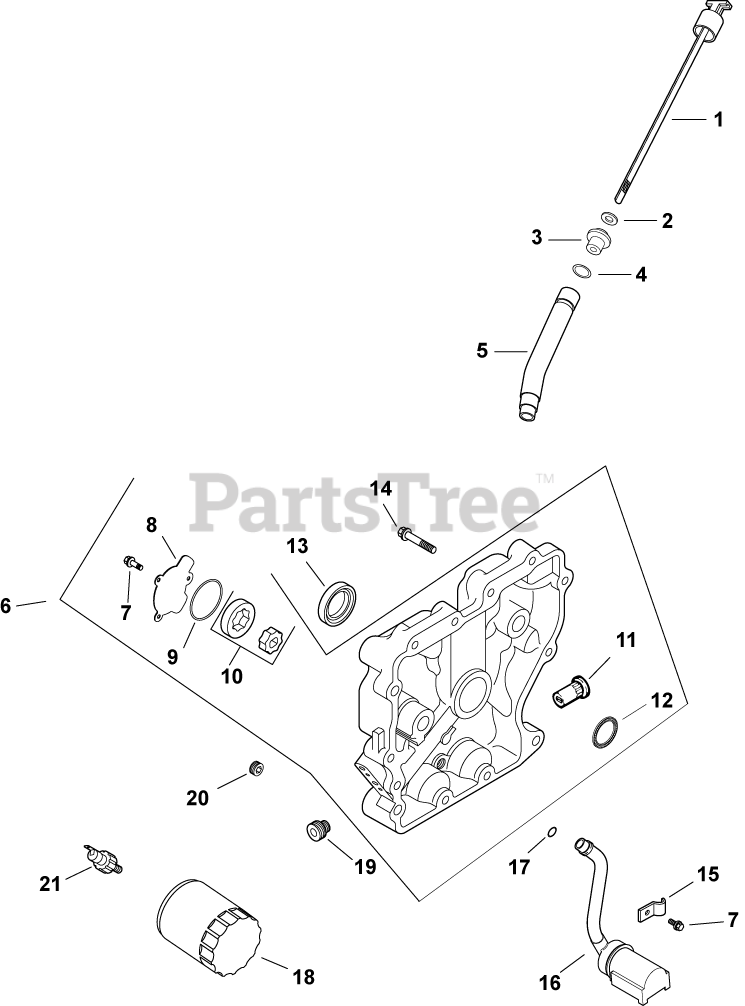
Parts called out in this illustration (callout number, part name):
3	SEAL USE 25 032 13-S
5	TUBE, OIL FILL
6	PLATE, CLOSURE & BEARING
7	SCREW,FLG THD FRM M5X0.8X16-(#25086398S)
8	COVER, OIL PUMP
9	O-RING (1.78" DIA)
10	PUMP ASSEMBLY, OIL
11	VALVE, OIL PRESSURE RELIEF
12	BEARING, CRANKSHAFT
13	SEAL, OIL
14	SCREW, FLG M8X1.25X45
16	KIT, OIL PICK-UP
17	O-RING (.5" DIA)
18	OIL FILTER
19	NIPPLE, OIL FILTER
20	PLUG, CTSK PIPE 1/8"
21	SENSOR, OIL PSI
